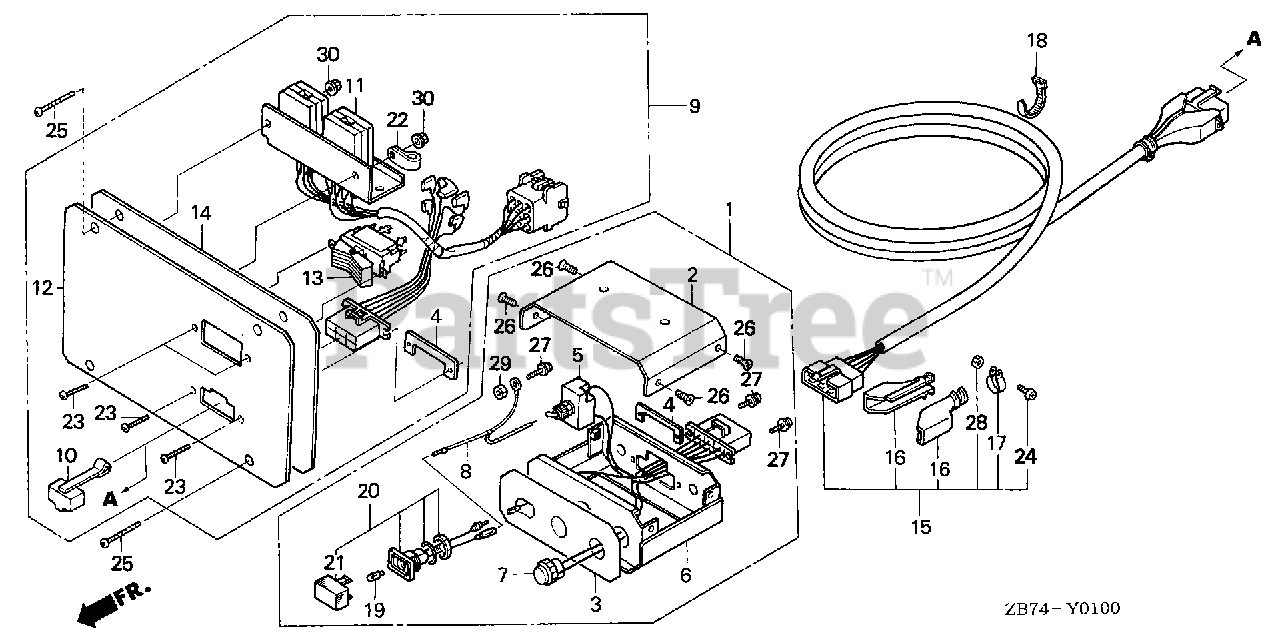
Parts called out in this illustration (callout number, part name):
1	BOX ASSY., SWITCH *R280* Use from Frame SN 1120560.
2	COVER (UPPER) *R8* (BRIGHT RED) Use up to Frame SN 1110009.
3	PLATE, SWITCH & INDICATOR Use from Frame SN 1001725.
4	PLATE, CONNECTOR SETTING
5	SWITCH, TOGGLE
6	PANEL, CONTROL *R8* (BRIGHT RED) Use up to Frame SN 1120559.
7	SWITCH, PUSH
8	WIRE, GROUND
9	CONTROL ASSY., REMOTE
10	COVER, REMOTE CONTROL CONNECTOR
11	RELAY ASSY.
12	MARK, REMOTE CONTROL
13	SWITCH ASSY.
14	PANEL, RELAY
15	CABLE, REMOTE CONTROL (10MM)
16	COVER, CONNECTOR
17	BAND
18	BAND B1, CABLE Use up to Frame SN 1001879.
19	BULB, WEDGE BASE (12V/2W) Use from Frame SN 1001725.
20	SOCKET ASSY., LAMP (GREEN) Use from Frame SN 1001725.
21	LENS (GREEN) Use from Frame SN 1001725.
22	CLIP (9MM)
23	SCREW, PAN (3X8) (CARBURETOR NO.)
24	SCREW, PAN (3X12)
25	SCREW, PAN (5X10)
26	SCREW, FLAT (4X8) Use from Frame SN 1001725.
27	SCREW-WASHER (4X12)
28	NUT, HEX. (3MM)
29	NUT, HEX. (4MM)
30	NUT, FLANGE (4MM)
